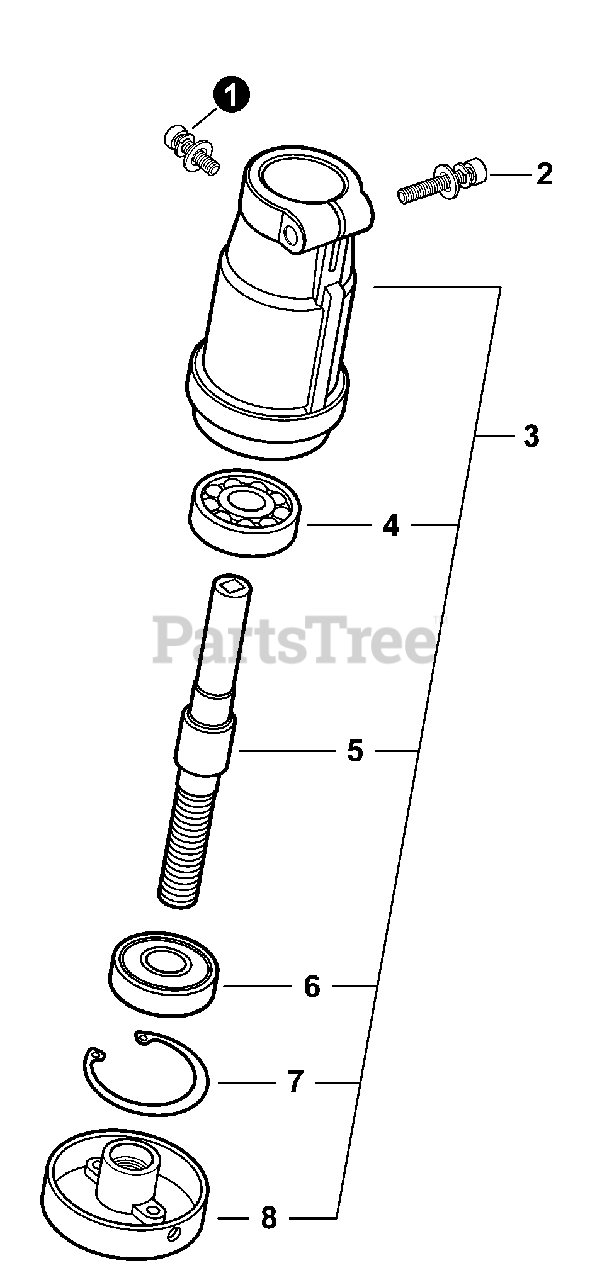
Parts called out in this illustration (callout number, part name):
1	SCREW 4×10
2	BOLT 5×25
3	GEAR CASE ASSY
4	BEARING, BALL 6200
5	SHAFT, GEAR
6	BEARING, BALL 6200
7	E-RING 30
8	PLATE, ADAPTOR - UPPER
